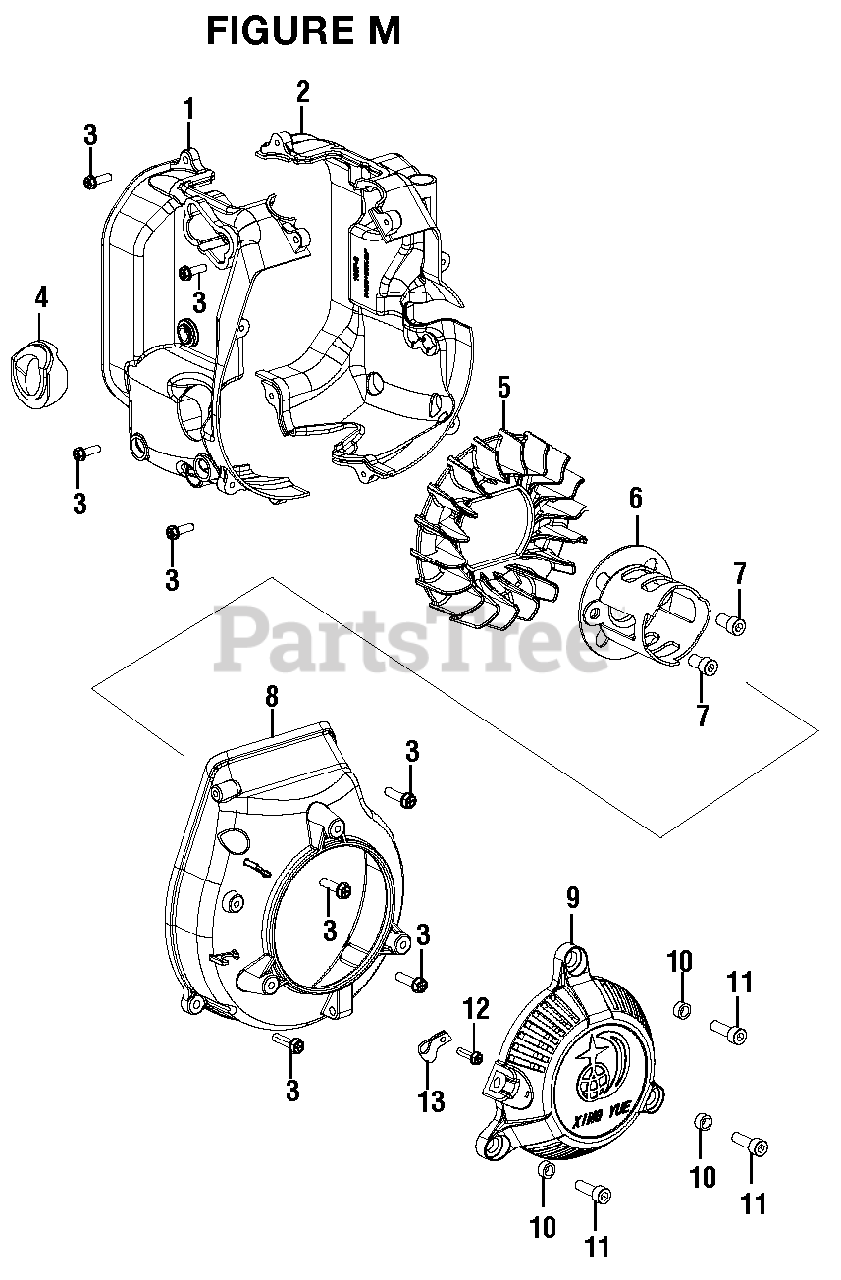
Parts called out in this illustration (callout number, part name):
1	Air Guide Sleeve (A)
2	Air Guide Sleeve (B)
3	Screw (M4.8 x 16 mm)
7	Screw (M6 x 10 mm, Hex Hd.)
9	Recoil Starter
10	Recoil Starter Bushing
11	Bolt (M5 x 16 mm, Flange Hex Hd.)
12	Screw (M4.2 x 10 mm)
13	Ignition Coil Wires Clamp
